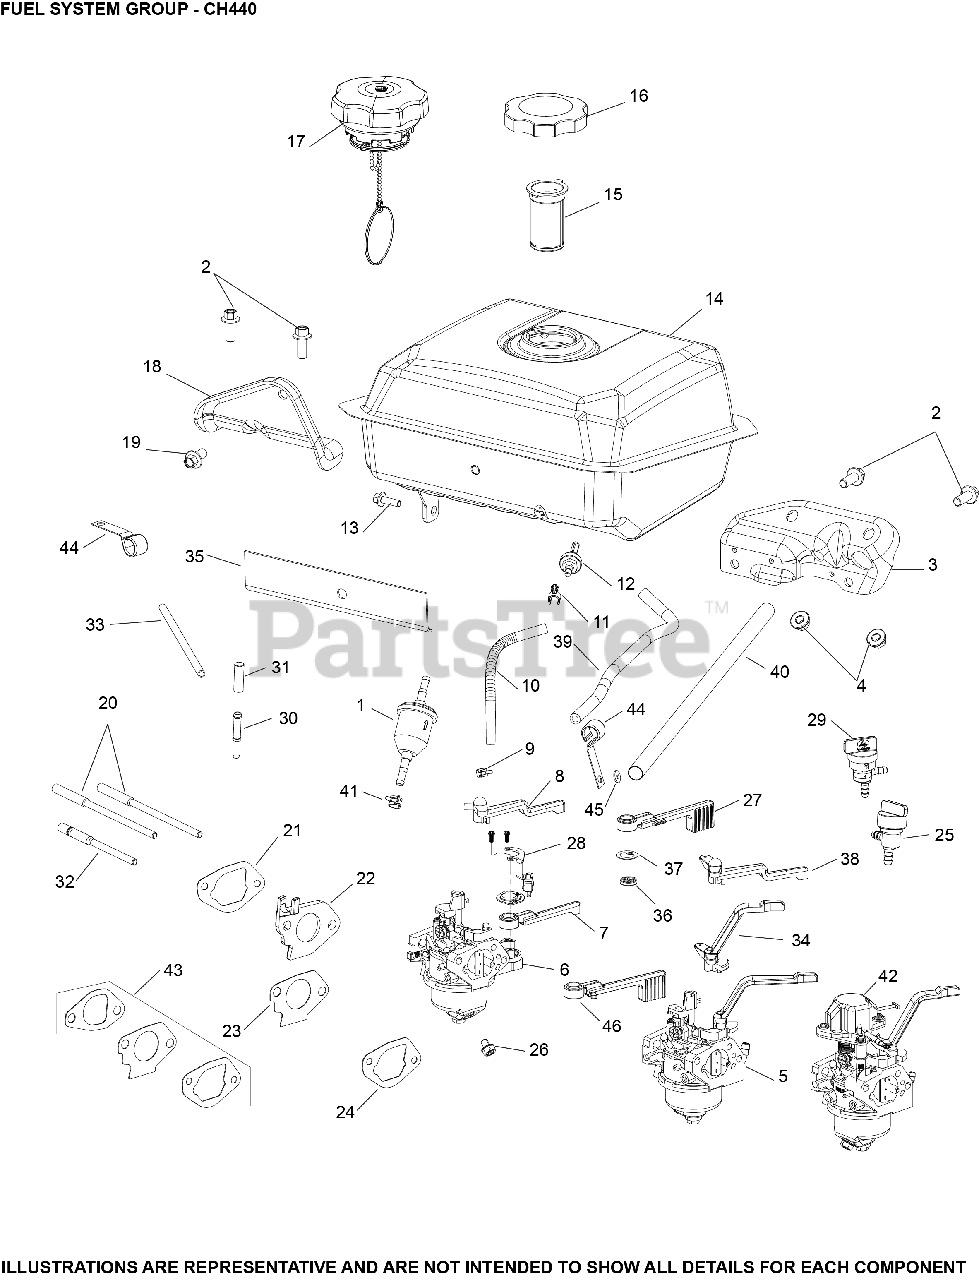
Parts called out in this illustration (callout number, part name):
2	SCREW, M8 X 20
3	BRACKET, FUEL SUPPORT ASSEMBLY
4	NUT, FLG M8X1.25
6	KIT, CARBURETOR COMPLETE USE 17 853 113-S
9	CLAMP, FUEL LINE
10	LINE, FUEL (10"-CUT TO LENGTH)
11	CLIP, FUEL HOSE
12	FITTING, FUEL ASSY
14	TANK, FUEL
15	FILTER, FUEL TANK
17	FUEL CAP, ASSEMBLY USE 17 173 19-S
18	BRACKET, FUEL SUPPORT
19	SCREW, FLG 8X1.25X16
20	STUD, CARBURETOR
21	KIT, GASKET INTAKE
22	KIT, INSULATOR
23	GASKET, CARB TO INSULATOR
36	SEAL, INLET VALVE
37	KIT, FUEL SCREEN
NI	KIT, HIGH ALTITUDE (4,000-8,000 FT)
NI	KIT, HIGH ALTITUDE (ABOVE 8,000 FT.)
NI	KIT, CARBURETOR REPAIR
